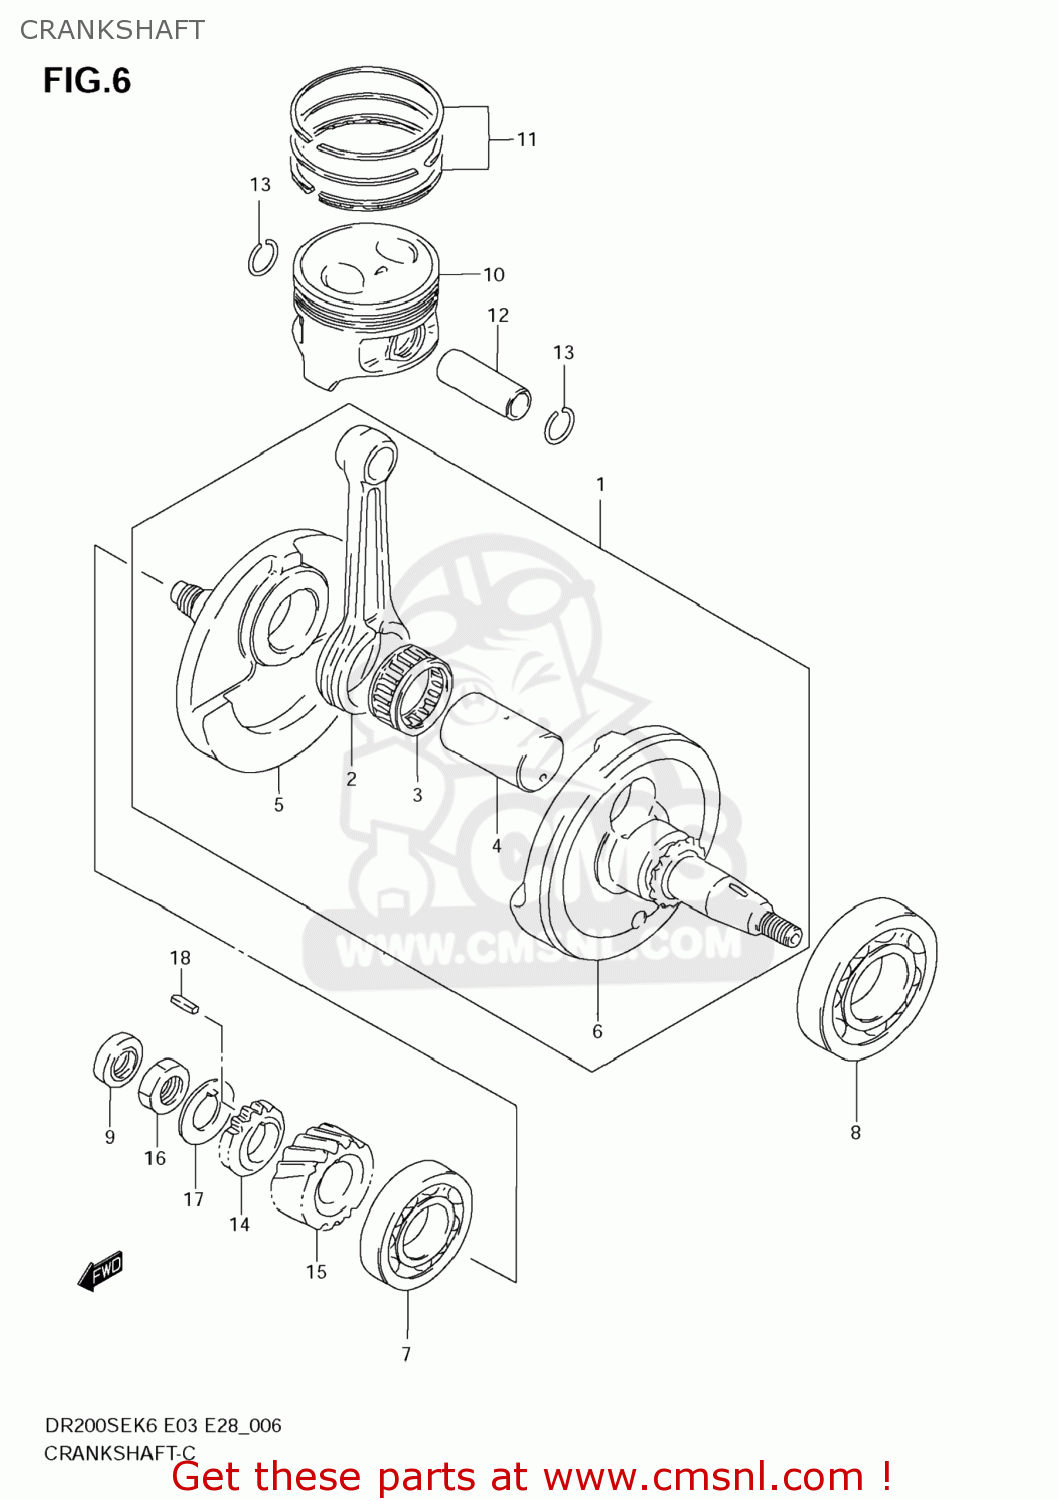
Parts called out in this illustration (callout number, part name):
1	CRANKSHAFT ASSY
2	CONNECTING ROD
3	BEARING(31X38X18)
4	PIN,CRANK
5	CRANKSHAFT,R
6	CRANKSHAFT,L
7	BEARING(28X68X18)
8	BEARING(35X72X17)
9	SEAL,OIL(12X21X7)
10	PISTON
11	RING SET,PISTON
12	PIN,PISTON
13	RING,SNAP 16MM
14	GEAR,OIL PUMP DRIVE(NT:15)
15	GEAR,PRIMARY DRIVE
16	NUT
17	WASHER
18	KEY
